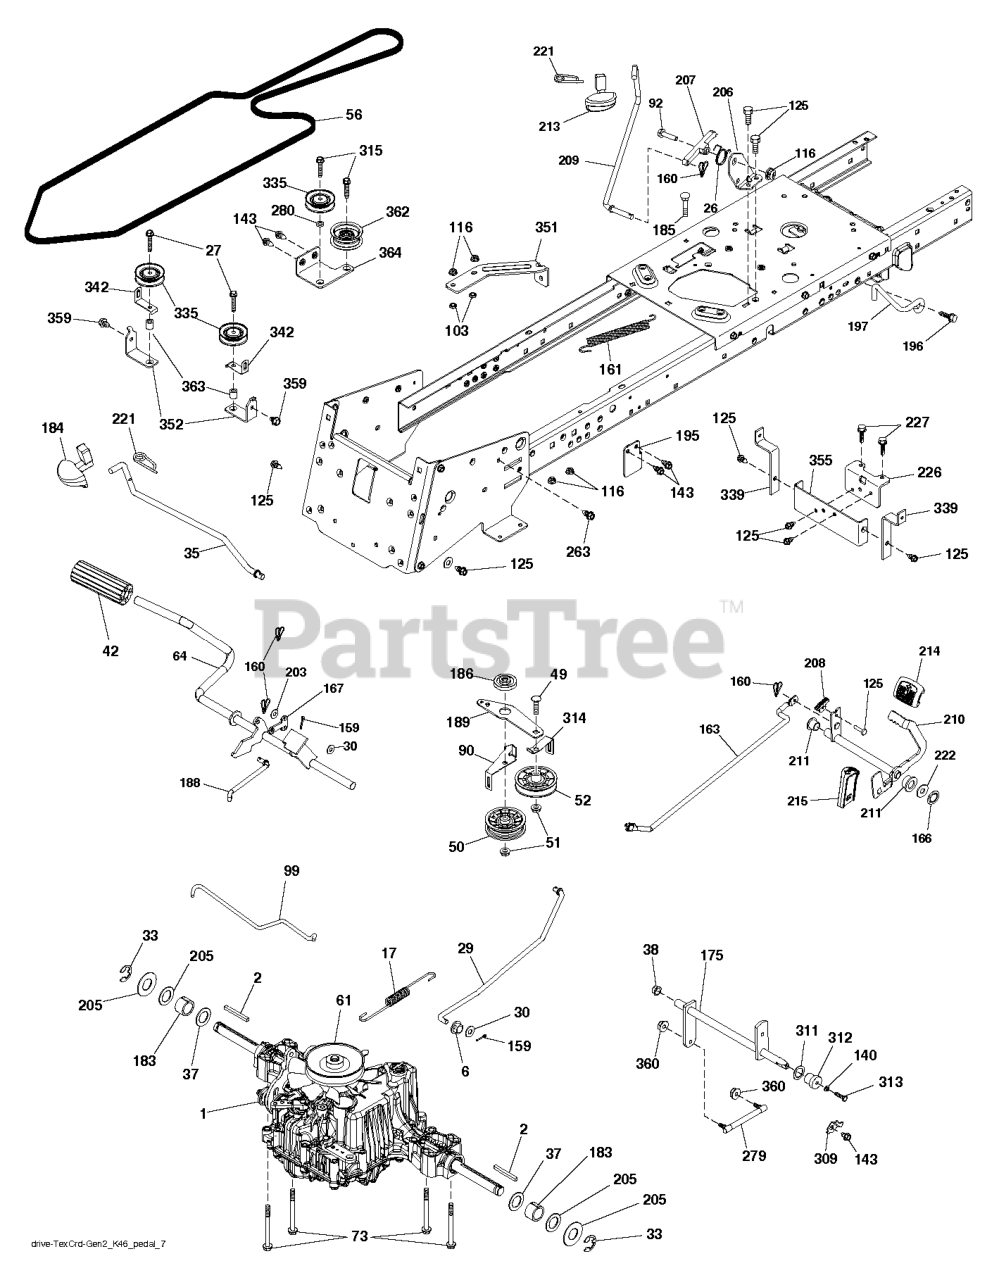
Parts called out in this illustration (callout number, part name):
2	SQUARE KEY
6	BUSHING.SNAP.NYL.BLK.
17	SPRING
26	SPRING.RETURN.CRUISE
27	SCREW
29	ROD ROD BRAKE K46 TCRD GEN 2
30	WASHER
35	ROD .BRAKE. PARKING. GT. HUSQ.
38	NYLINER SNAP 5/8" ID
42	PEDAL COVER T
50	IDLER.FLAT.910.OFFSET
51	NUT LOCK FLG 3/8-16 UNC
52	IDLER.V-GROOVE.910.OFFSET
56	BELT BELT DRIVE GROUND 114.25
61	PULLEY PULLEY INPUT FLANGED TR
64	SHAFT.ASM.PEDAL.BRK.CNTR
73	BOLT HEX 5/16-18 GR 5
90	KEEPER KEEPER BELT CLUTCHING T
92	BOLT
99	ROD ROD BYPASS CRD TEX GEN 2
103	JAM NUT TI
116	NUT LOCK HEX FLANGE 5/16-18
125	SCREW
140	LOCKWASHER
143	Screw 5/16-18 x 1/2 Hex, Self Tapping 5/16-18 x 1/2
159	COTTER PIN
160	RETAINER CLIP
161	SPRING, RETURN LT
163	ROD ROD CONTROL SHIFT PEDAL TC
166	NUT.PUSH.625
167	LATCH.BRAKE.SPRING
175	SHAFT SUBASM.SHAFT.CROSS.SHIFT
183	SPACER AXLE
184	RB HANDLE.PARKG.BRK.HUS/PRED
186	SPACER.RETAINER
188	RP.LINK.CLUTCH.GROUND.DRIVE
189	BELLCRANK BELLCRANK GROUNDDRI
195	BRACKET.ROD.BRAKE
196	SCREW 3/8-16X1
197	CLUTCH.ANTIROTATION.WIREFORM.
203	WASHER
206	BRACKET.MOUNT.CRUISE.LATCH
207	LATCH.CONTROL.CRUISE
208	GEAR.SECTOR.CONTROL.CR
209	ROD.CONTROL.CRUISE.GT.
210	ROCKER.ASM.PEDAL.CONTR
211	BEARING.NYLON
213	KNOB.CONTROL.CRUSIE.HU
214	PEDAL.FORWARD.PAD.TEX
215	PEDAL RUBBER REVERSE
221	RETAINER.SPRING.CLIP.H
222	WASHER 21/32 X 1-1/4 X 10 GA.
226	BRACKET.MOUNT.TORQUE.K46.TLT
227	SCREW.THDROL.5/16-18X3/4.TTY
263	SCREW, 3/8-16X3/4
279	LINK SUBASM. LINK AND STUD
280	WASHER T
309	PLATE.FASTENING.CROSS.SHAFT
311	WASHER NYL
312	HUB.TAPERED.ROUND.CRD
313	BOLT
314	RETAINER KEEPER BELT
315	BOLT.5/16-18X1.25
335	PULLEY.V-IDLER.
339	STRAP STRAP TORQUE K46 CRD TE
342	BELT GUIDE
351	BRACKET BRACKET DECK SWAY
352	BRACKET BRACKET.IDLER
355	STRAP STRAP TORQUE K46 CRD TEX
359	SCREW LT.3/8-46X5/8
360	NUT NUT HEX CENTERLOCK 5/16-24
362	IDLER.FLAT.2.25.INCH
363	SPACER SPACER 343X63X.62
364	BRACKET BRACKET IDLER CRD TEX
